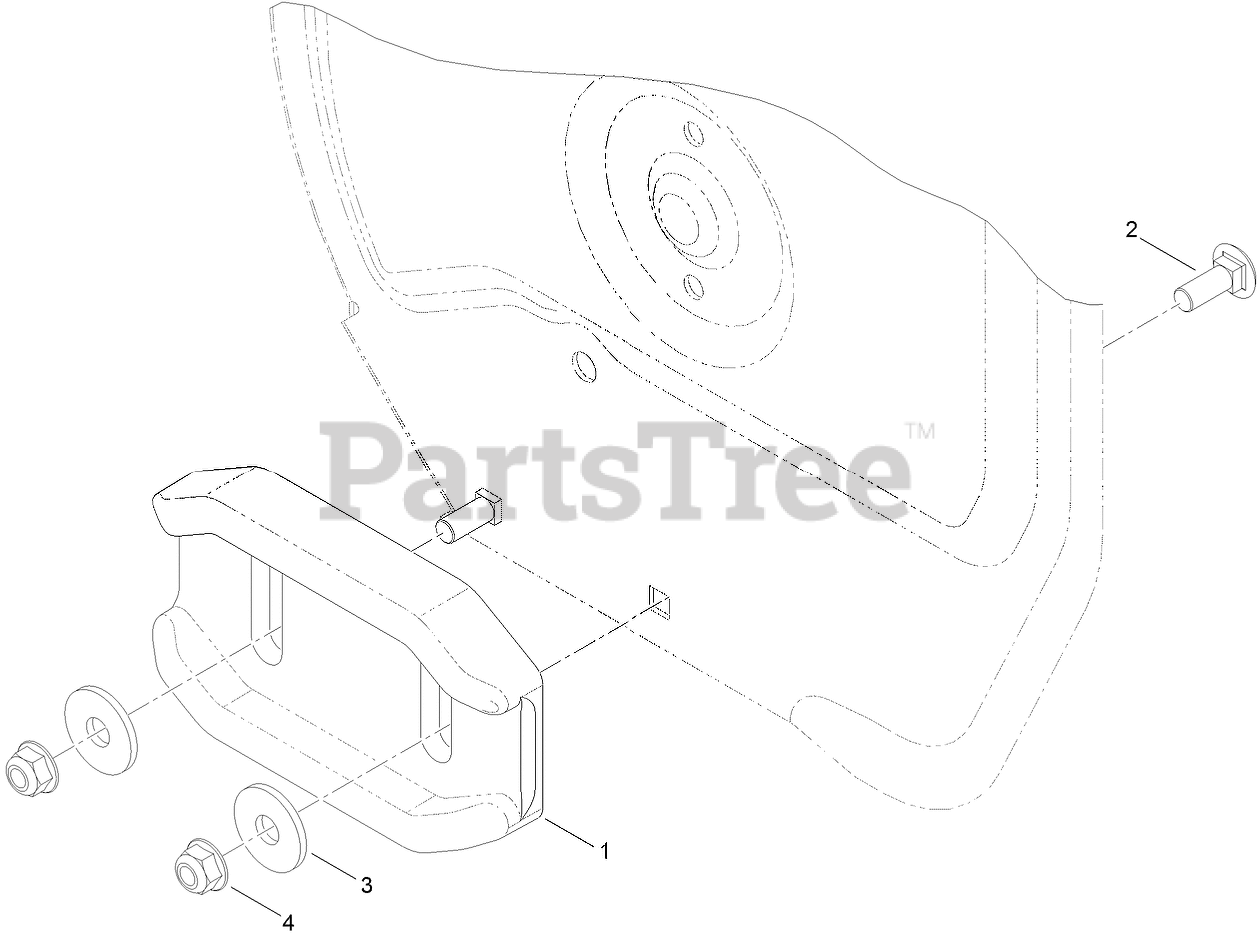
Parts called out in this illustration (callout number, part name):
1	SKID-CAST
2	SCREW-CARR
3	WASHER
4	NUT-HF, NI
